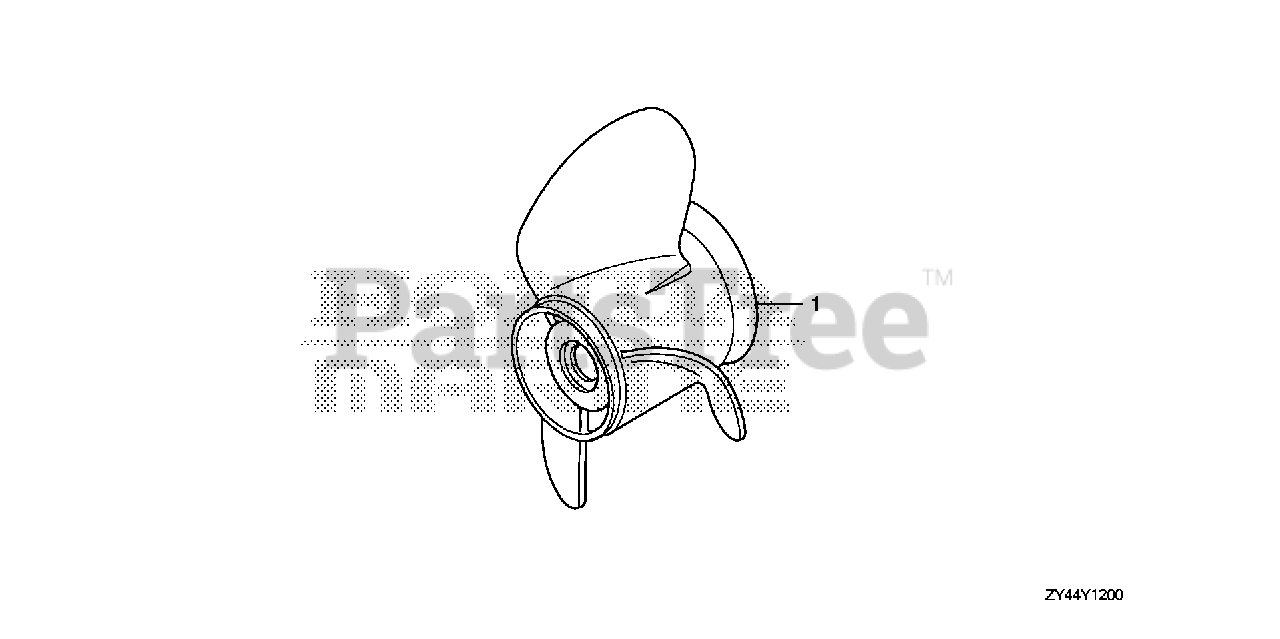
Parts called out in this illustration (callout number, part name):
1	PROPELLER, THREE-BLADE (14-1/2X15) (C/R)
1	PROPELLER, THREE-BLADE (14-1/4X17) (C/R)
1	PROPELLER, THREE-BLADE (14X19) (C/R)
1	PROPELLER, THREE-BLADE (14X21) (C/R)
1	PROPELLER, THREE-BLADE (14-1/2X23) (C/R)
